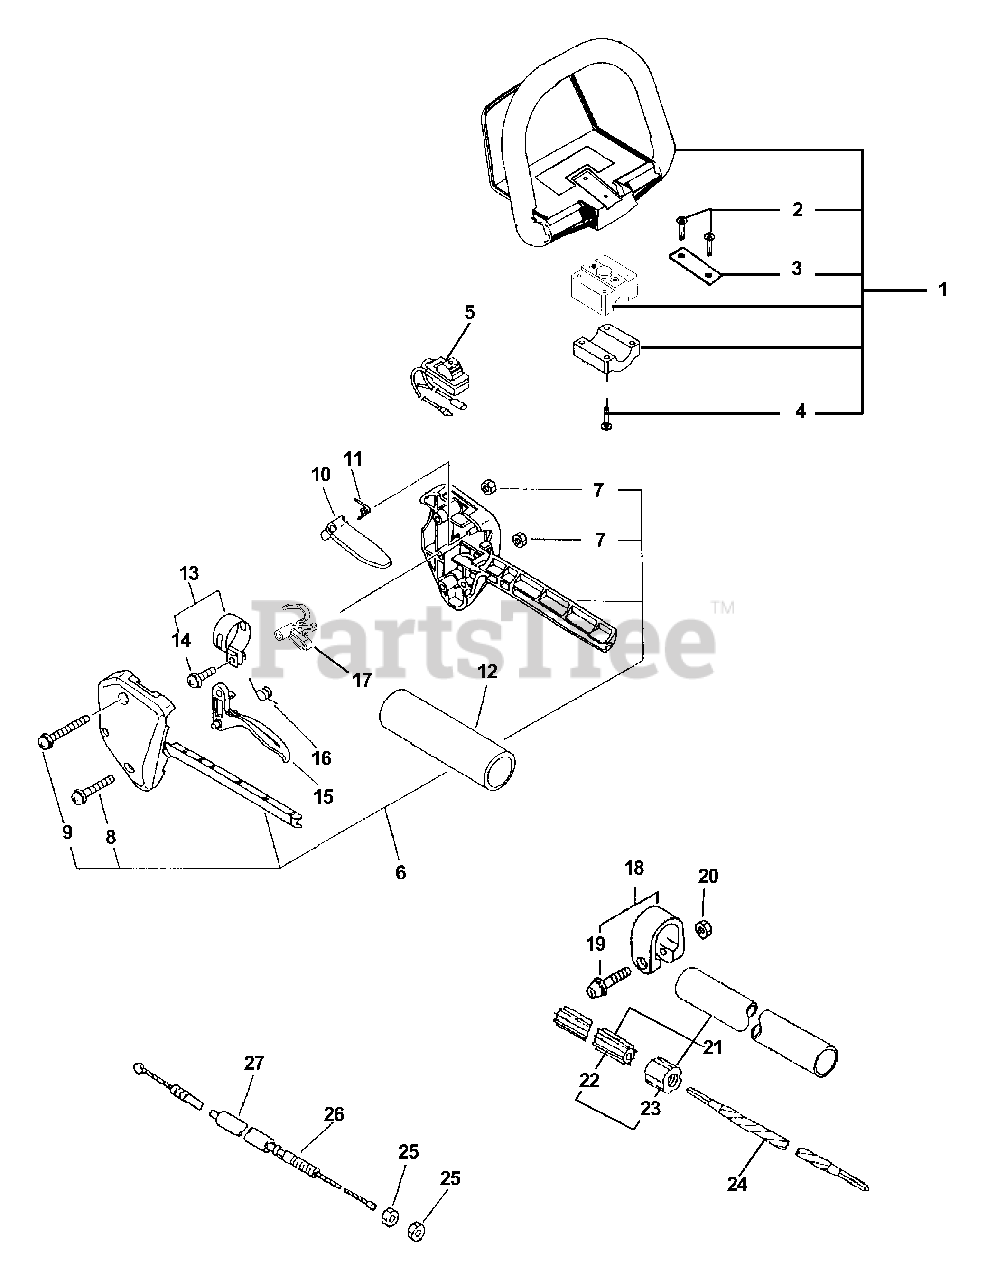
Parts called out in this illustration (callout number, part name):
1	HANDLE ASSY - FRONT
2	SCREW - 5X30
4	SCREW - 5
5	IGNITION SWITCH ASSY
6	THROTTLE BRACKET SET
8	SCREW - 5X25
9	SCREW - 5X35
10	LEVER, TRIGGER LOCKOUT
11	SPRING, LOCKOUT LEVER
12	GRIP, HANDLE - REAR
13	CLAMP KIT
14	SCREW - 5X14
15	TRIGGER, THROTTLE
16	SPRING, TRIGGER
17	LOCKOUT, THROTTLE
18	CLAMP
19	SCREW - 5X28
21	MAIN PIPE ASSY
22	LINER - FLEXIBLE
24	DRIVESHAFT - FLEXIBLE
26	CABLE, THROTTLE
27	TUBE, PROTECTIVE - CORRUGATED
